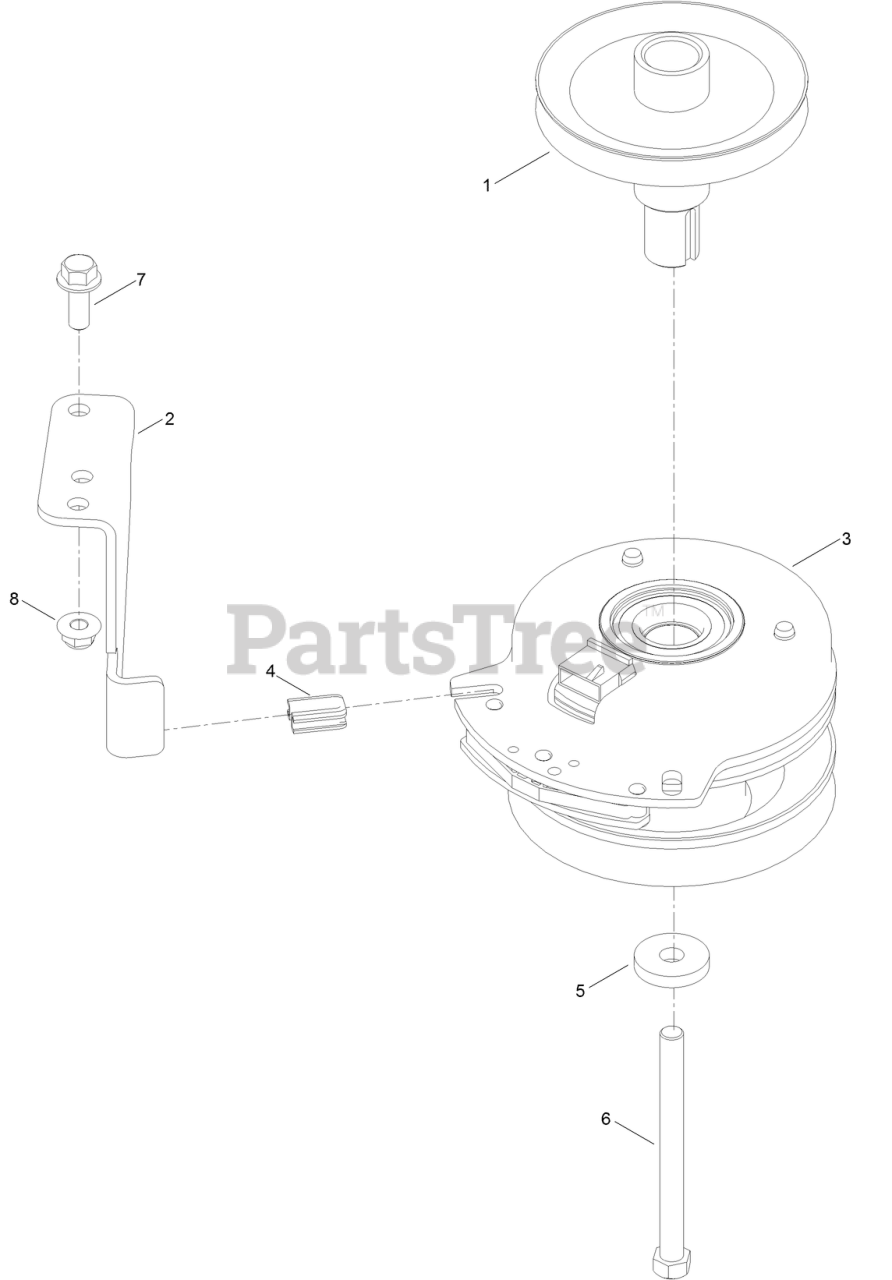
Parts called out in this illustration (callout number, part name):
1	PULLEY-ENGINE
2	STOP-CLUTCH (WIDE)
3	CLUTCH-PTO
4	ISOLATOR-CLUTCH
5	WASHER
6	SCREW-HH
7	SCREW-HHF
8	NUT-HF, NI
